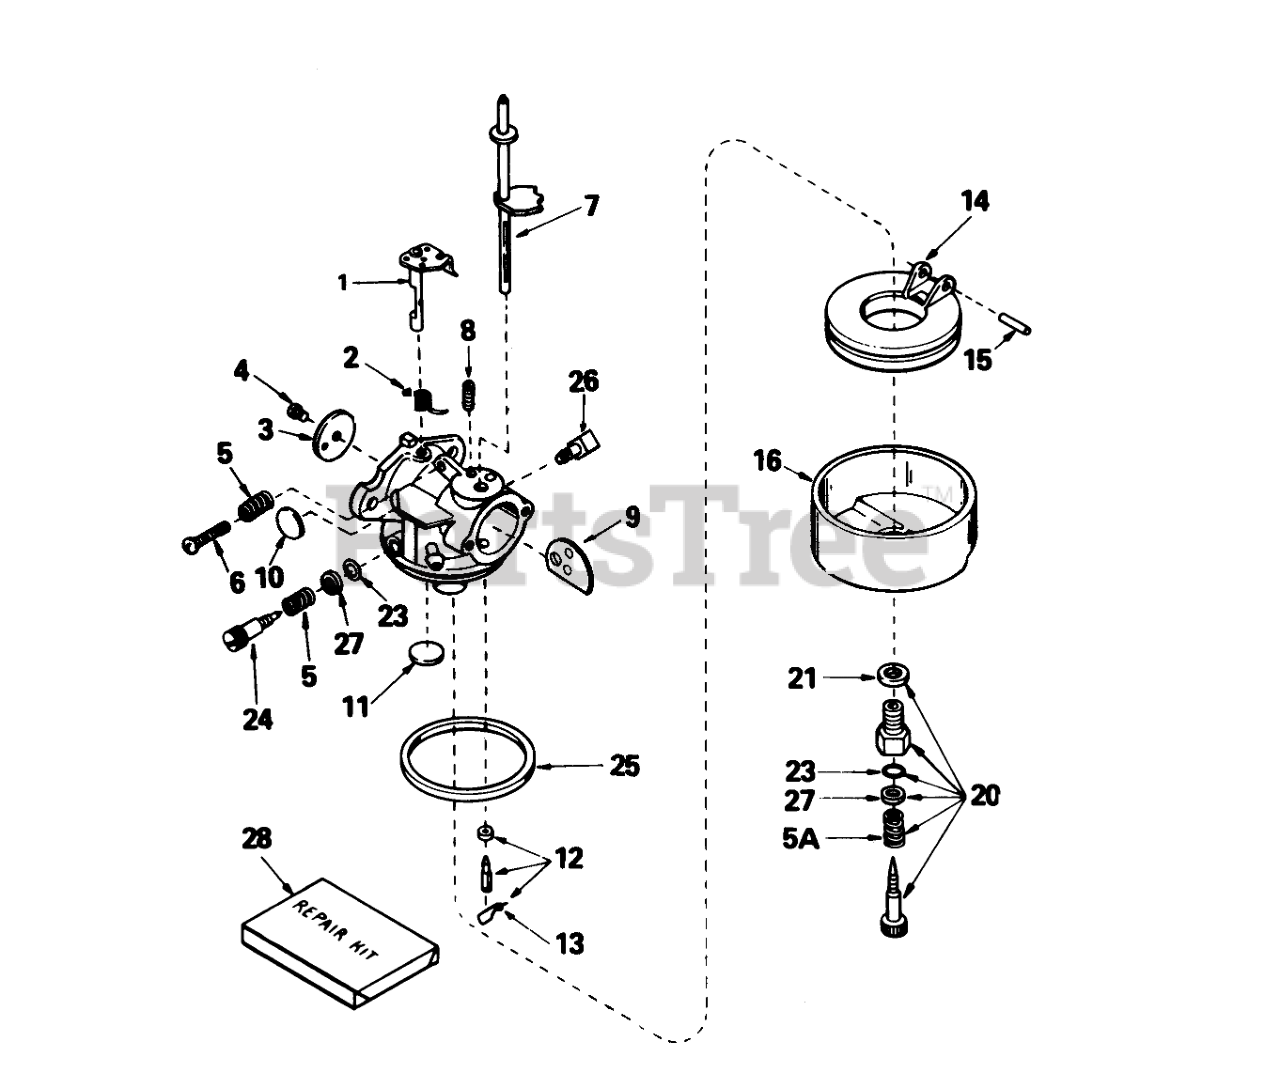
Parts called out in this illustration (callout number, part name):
1	Throttle Shaft and Lever ASM
2	Spring-Return, Throttle
3	Shutter-Throttle
4	Screw-Shutter
5	Spring-Tension
6	Screw-Throttle Crack Screw / Idle Speed
7	Shaft-Choke
8	Spring-Positioning, Choke
9	Shutter-Choke
10	Plug-Welch, Idle Mixture Well
11	Plug-Welch, Atmospheric Vent
12	Inlet Needle-Seat 8 Clip Assy. (Incl. Ref. #13)
13	Clip-Spring
14	Float
15	Shaft-Float
16	Bowl-Float (no drain)
20	Adjustment Screw Assy.-Main (Incl. Ref. #5A, 21, 23 & 27)
21	Washer-Bowl Nut
23	"O"Ring
24	Screw, Idle Adj.
25	O Ring-Bowl, Float
26	Fitting-Fuel
28	Kit-Repair
